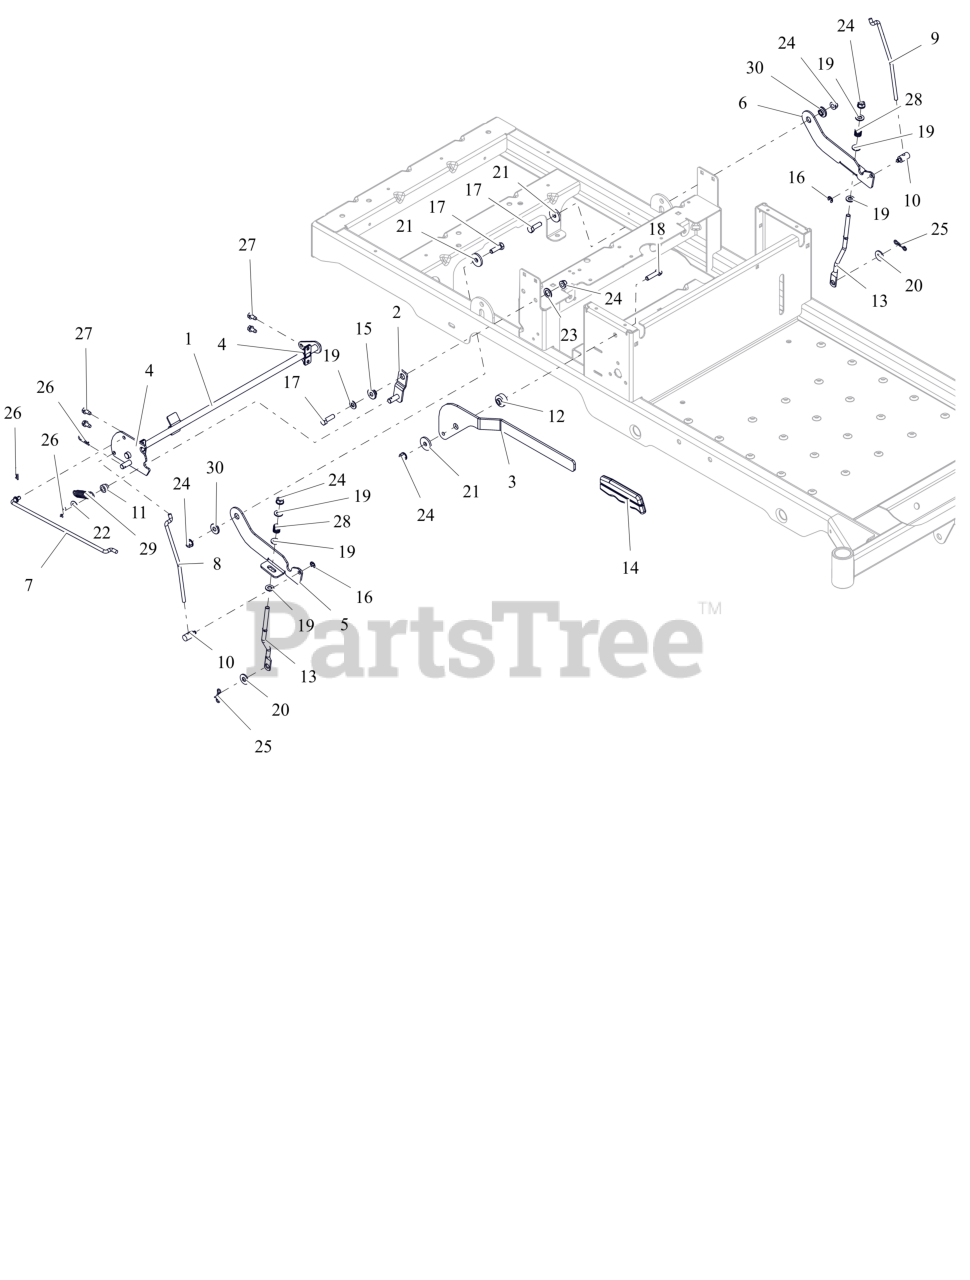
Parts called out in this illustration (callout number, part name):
1	WELDMENT, BRAKE SHAFT
2	WELDMENT,DETENT ARM
3	HANDLE, PARKING BRAKE
4	BUSHING-.50 CLAMP BLOCK MOLDED
5	LATCH,RH NETURAL
6	LATCH,LH NETURAL
7	LINK, BRAKE HANDLE
8	LINK, NEUTRAL RH
9	LINK, NEUTRAL LH
10	TRUNION, 1/4-20
12	SPCR,BRAKE .32X.49X.192X1.00
13	LINK, BRAKE COG
14	GRIP, PARKING BRAKE (YELLOW)
15	BSHG-FLG .32X.500X.344X.880
16	E-RING, .250 X .025
17	BLT,HEX .31-18X1.00 G5 ZCC
18	BLT, HEX .31-18X1.25 G5 ZCC
19	WSHR,FLT .344X.688X.065 ZCC
20	WSHR,FLT .375X.875X.083 ZCC
21	WSHR, FLT .340X1.125X.135 ZCC
22	WSHR, FLT .385X.745X.030 ZCC
23	WSHR, FLT .520X.827X.062 ZCC
24	NUT,LK-CTR-FLG .31-18 GF ZCC
25	PIN, BOWTIE #72 ZCC
26	PIN, HAIR #213 .08X1.19 ZCC
27	SCR-TAP .25-20X.50 HWH ZCC
28	SPRING, COMPRESSION
29	SG-TENS .072X.565X1.87
30	BSHG, FLG .325X.499X.26X.88
